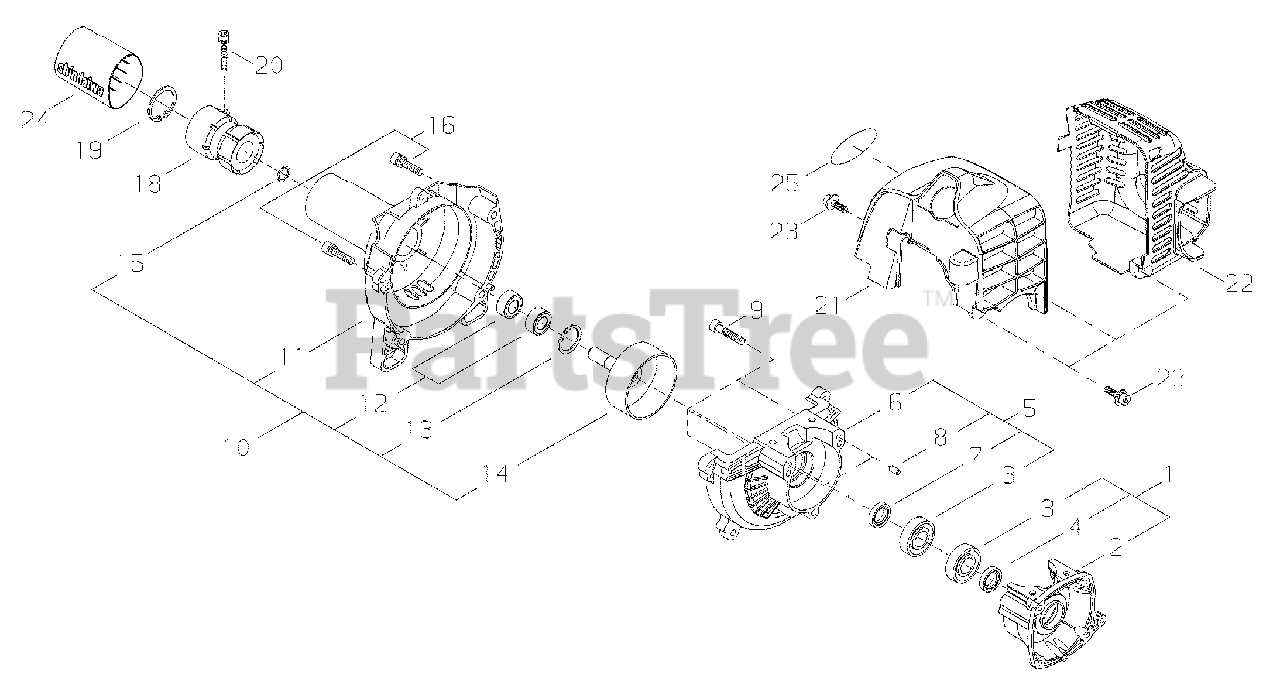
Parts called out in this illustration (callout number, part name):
1	CRANKCASE ASSY, S
2	CRANKCASE S
3	BEARING, BALL 6001 C3
4	SEAL, OIL 12
5	CRANKCASE ASSY, M
6	CRANKCASE M
7	SEAL, OIL 12
8	PIN, LOCATING Ø4×8
9	BOLT 5×25
10	COVER ASSY, FAN
11	COVER, FAN
12	BEARING, BALL 6000 DDU
13	RING, SNAP Ø26
14	DRUM, CLUTCH
15	RING, SNAP WR10
16	BOLT M5×18
18	CUSHION, AV
19	RING, SNAP Ø40
20	BOLT M5×22
21	COVER, ENGINE
22	COVER, MUFFLER
23	BOLT M4×16
24	PROTECTOR
25	LABEL - MODEL 242
